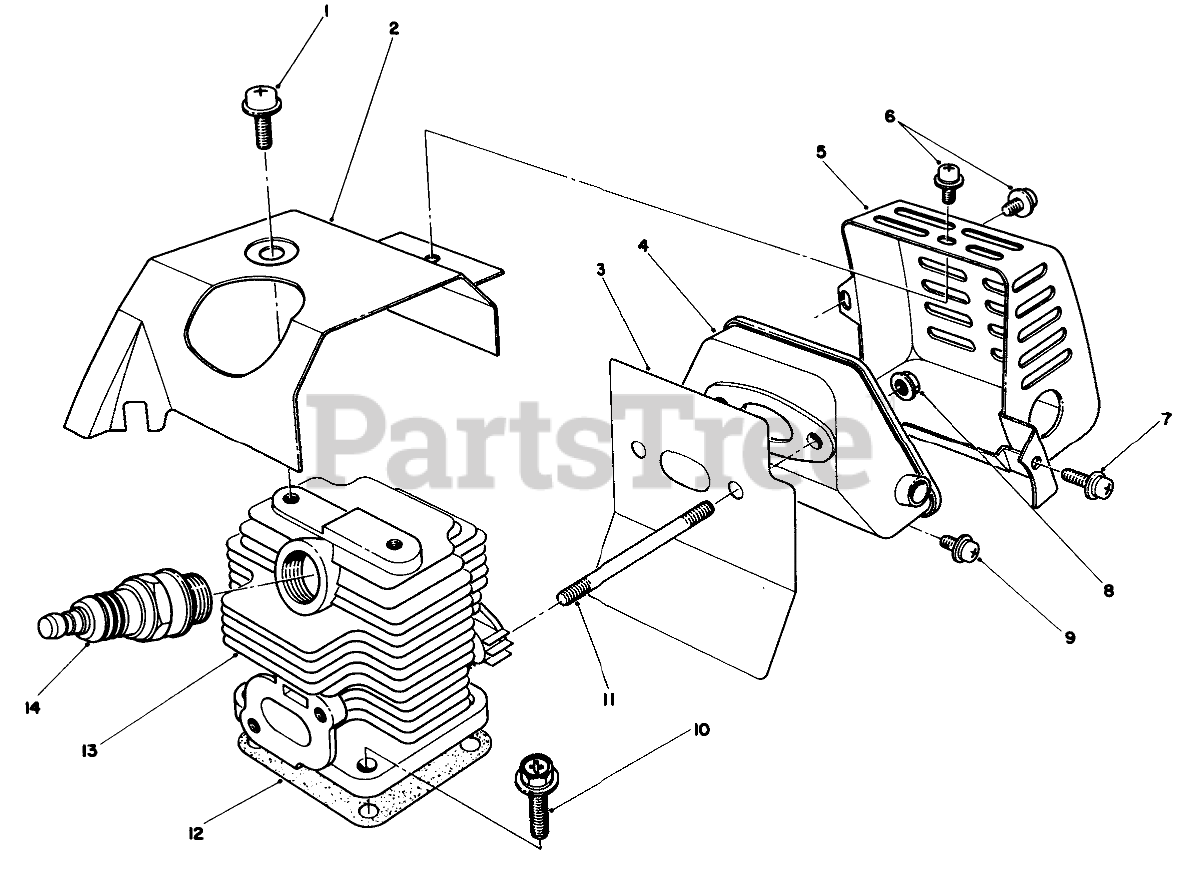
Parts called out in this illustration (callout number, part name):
1	Screw & Dishes
2	CYLINDER COVER
3	Gasket-Muffler
4	MUFFLER
5	COVER, MUFFLER
6	Screw & Washer
7	Screw & Washer
8	NUT, FLANGE
9	Screw & Washer
10	BOLT AND WASHER
11	Bolt-Stud
12	CYLINDER GASKET
13	Cylinder (Incl. Ref. #11)
14	SPARK PLUG (NGK)
